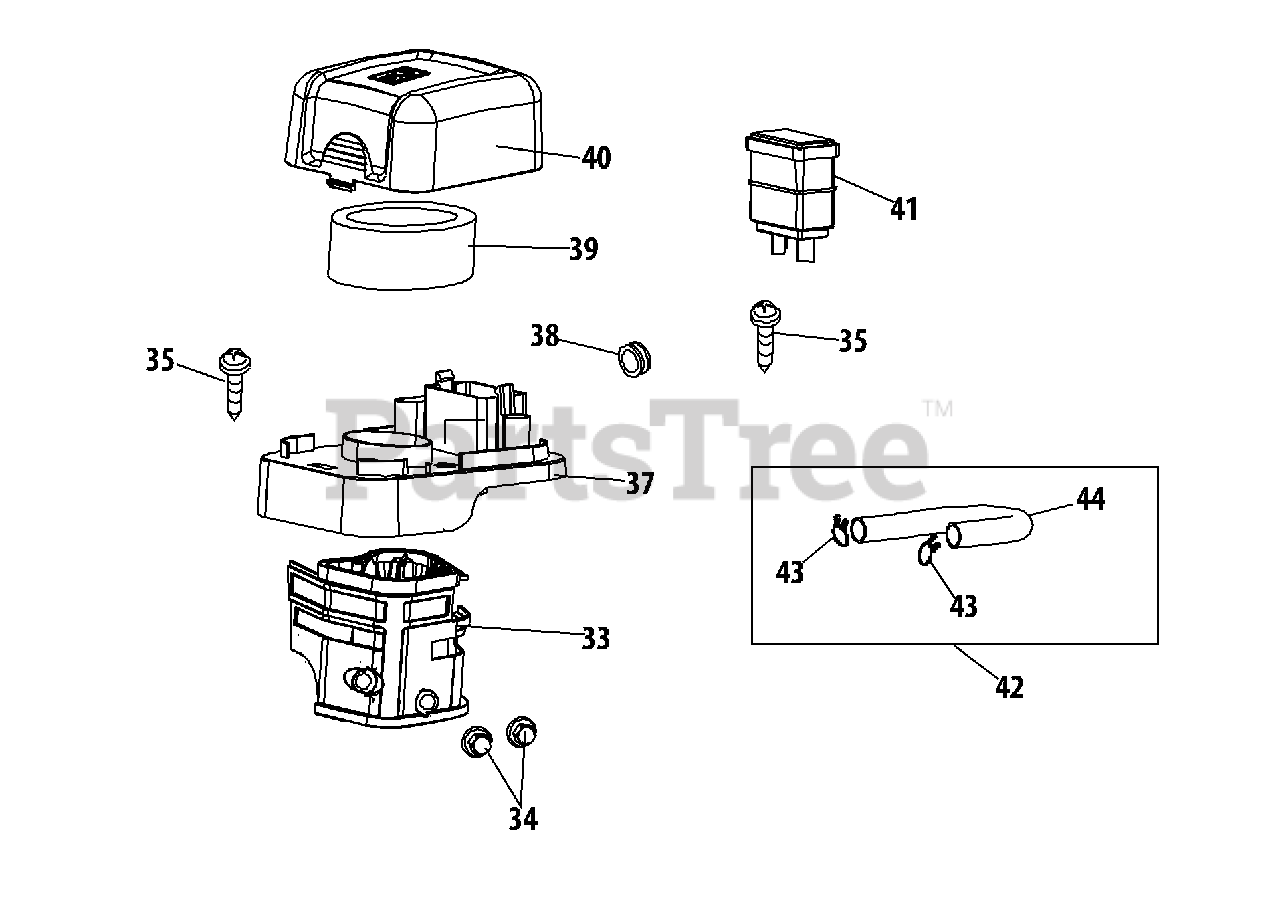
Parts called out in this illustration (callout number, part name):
33	Air Cleaner Housing
35	Self-Tapping Bolt M4.2×16
37	Silencer Plate
38	Rubber Shock Pad
39	Air Filter
40	Air Filter Cover
41	Carbon Canister
42	Primer Hose
44	Breather Hose
